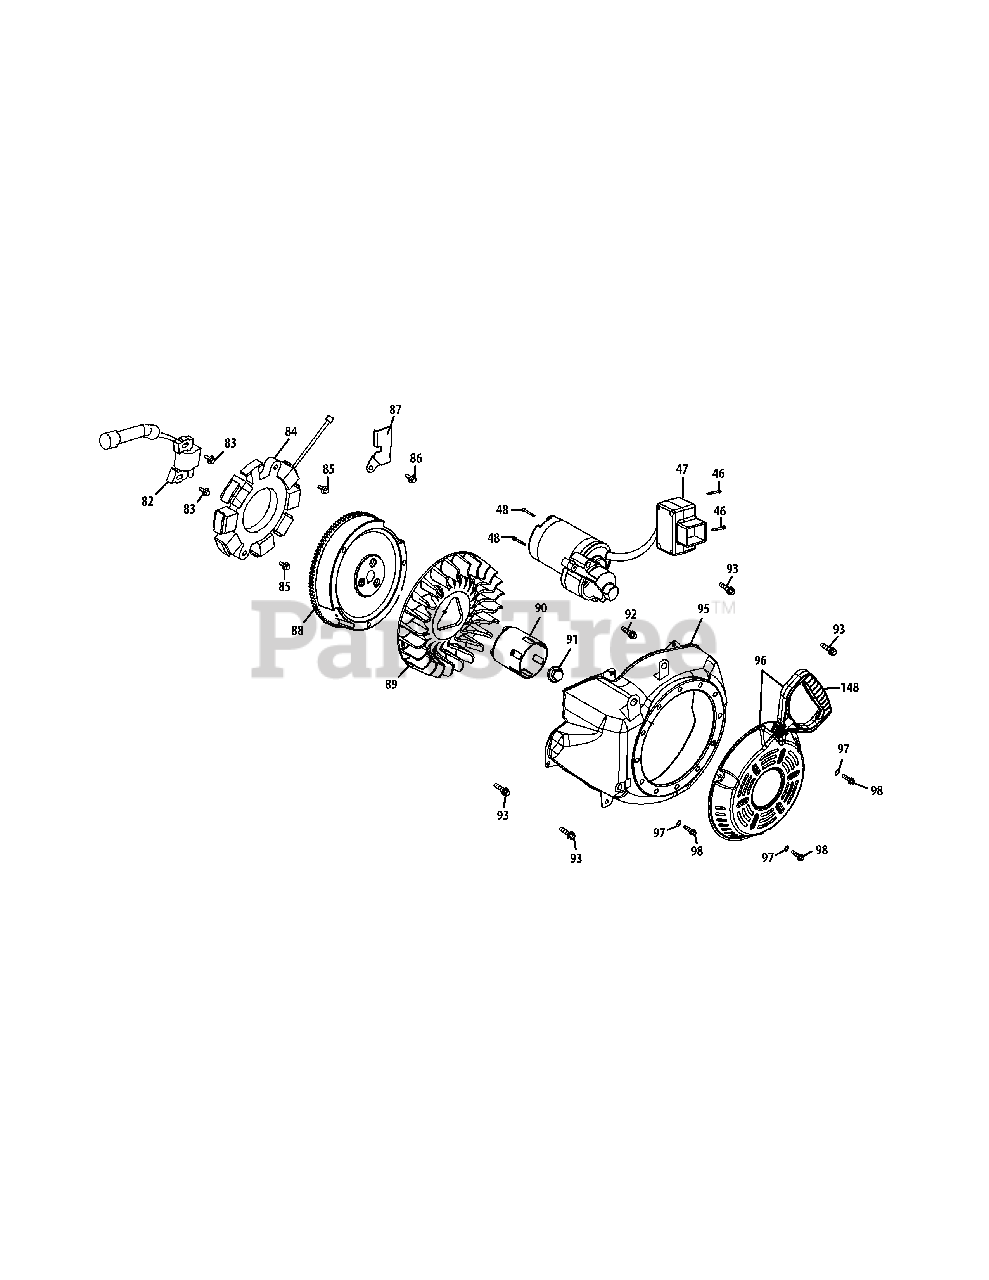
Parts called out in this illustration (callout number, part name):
46	Bolt M4×55
47	Electric Starter
48	Bolt M8×55
82	Ignition Coil Assembly
83	Ignition Coil Bolt
84	Coil Assy.Charge
85	Bolt M6×30
86	Bolt M6×8
87	Alt Wire Clamp Brkt
89	Fan Cooling
90	Pulley Starter
91	Nut Special M16×1.5
92	Bolt M6×16
93	Bolt M6×12
95	Blower Housing
96	Recoil Starter
97	Gasket 6
98	Bolt M6×10
148	Starter Handle
